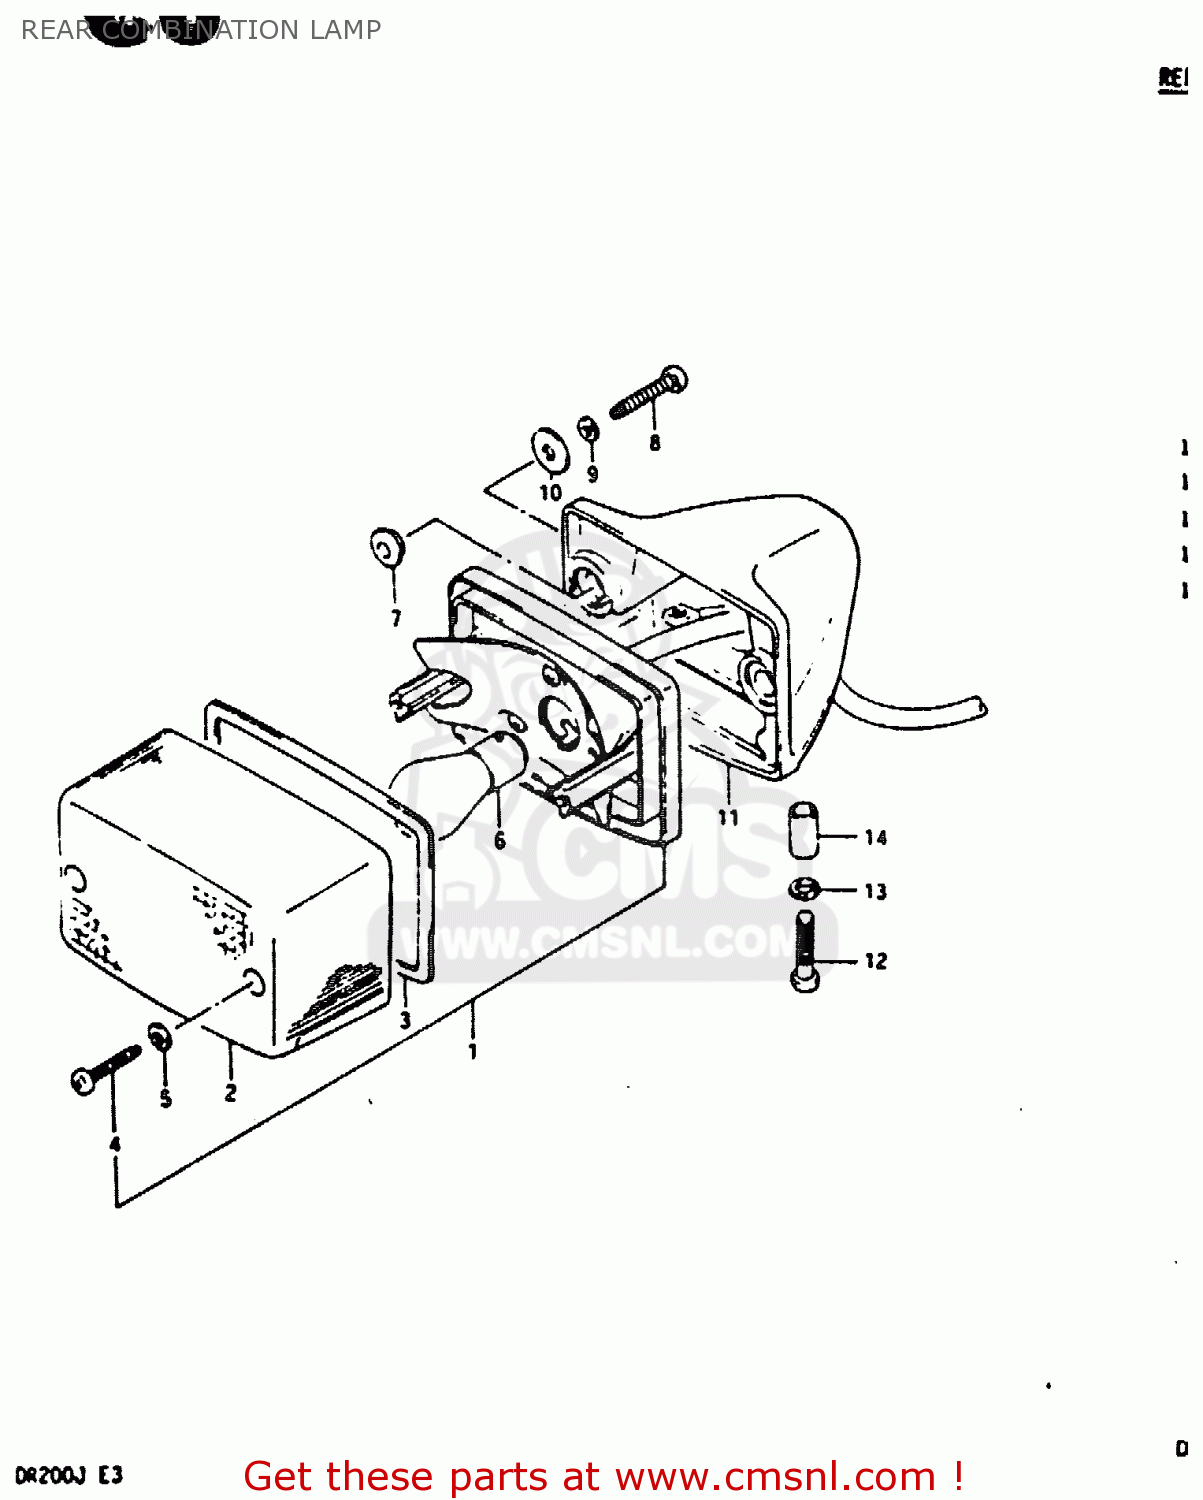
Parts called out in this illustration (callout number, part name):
1	LAMP UNIT,REAR COMBINATION
2	LENS,REAR COMBINATION LAMP
3	GASKET,RR COMBI LAMP LENS (NAS)
4	SCREW
5	GASKET (NAS)
6	BULB(6V5W,TOKAI DENSO)
7	SPACER,RR COMBI
8	SCREW
9	WASHER,LOCK
10	WASHER
11	BRACKET UNIT,TAIL LAMP
12	SCREW
13	WASHER,LOCK
14	SPACER(6.4X9.2X12)
